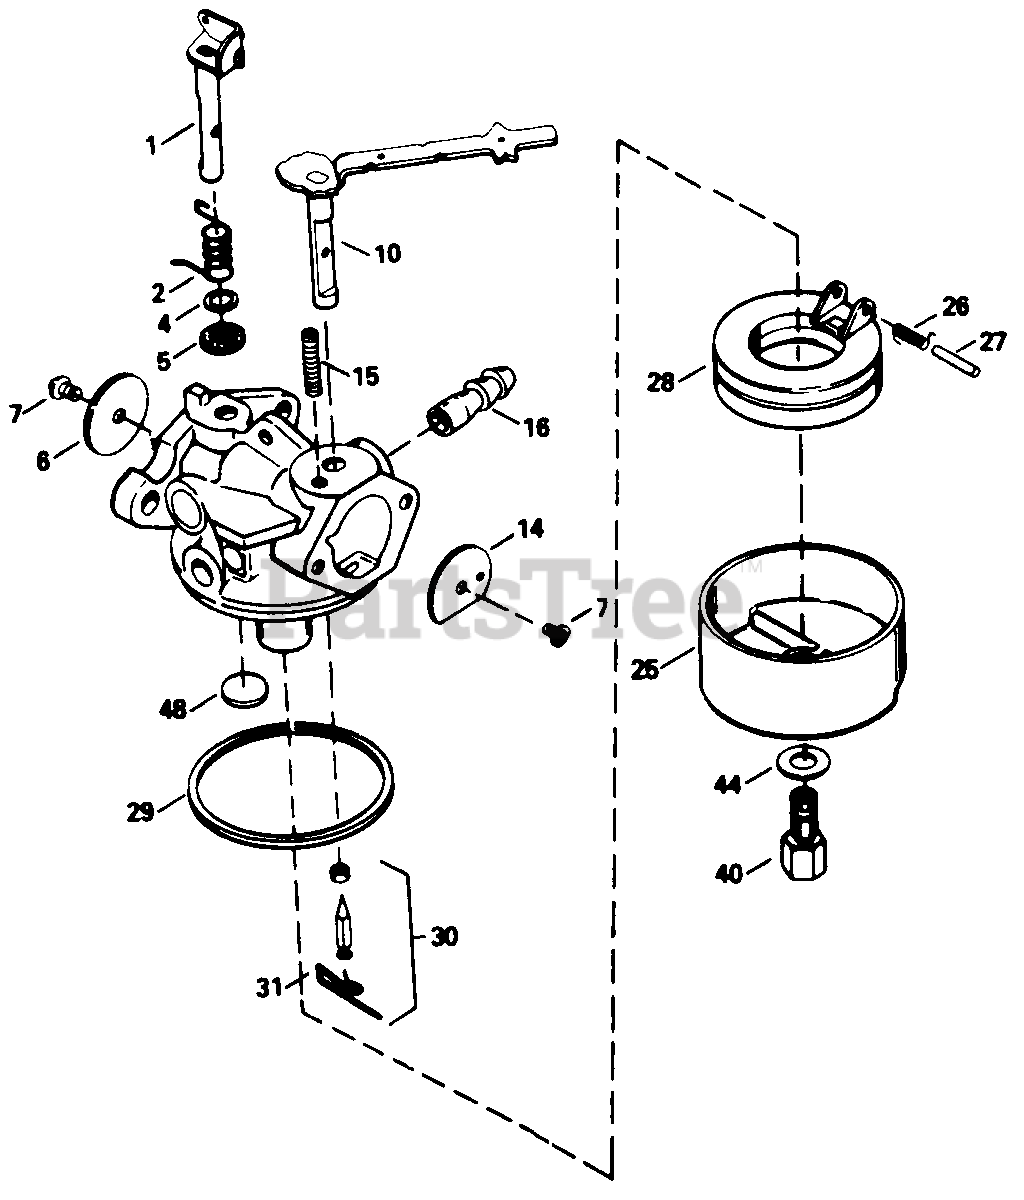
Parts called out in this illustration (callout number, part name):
1	Throttle Shaft & Lever Ass'y.
2	Throttle Return Spring
4	Dust Seal Washer (Throttle)
5	Dust Seal (Throttle)
6	Throttle Shutter
7	Throttle & Choke Shutter Screw
10	Choke Shaft & Lever Ass'y.
14	Choke Shutter
15	Choke Positioning Spring
16	Fuel Fitting
25	Float Bowl
26	Float Dampening Spring
27	Shaft, Float
28	Float
29	O-Ring, Float Bowl to Body
30	Inlet Needle, Seat & Clip
31	Spring Clip
40	High Speed Bowl Nut
44	Bowl Nut Washer
48	Welch Plug, Atmospheric Vent
